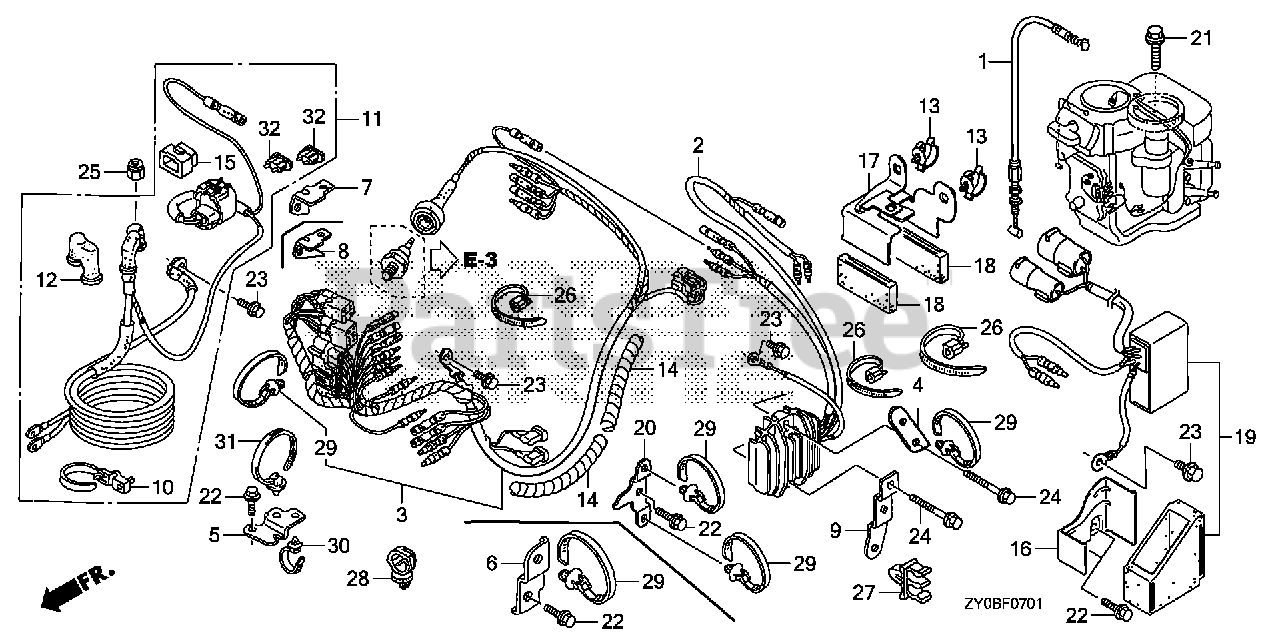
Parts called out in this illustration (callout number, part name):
1	CABLE, NEUTRAL STARTING
2	RECTIFIER ASSY., REGULATOR
3	WIRE HARNESS ASSY. (REMOTE CONTROL)(PT)
4	BRACKET, CLIP F
5	BRACKET, STARTER CABLE
8	BRACKET, FUSE CASE (PT)
9	BRACKET, E-CLIP
10	BAND, WIRE
11	CABLE ASSY., STARTER (PT)
12	COVER, MAGNETIC SWITCH TERMINAL
13	CLAMP, WIRE
14	TUBE, SPIRAL A
15	COVER ASSY., FUSE (20A)
16	BRACKET, RELAY (PT)
17	BRACKET, CONNECTOR A
18	GROMMET, CONNECTOR
19	RELAY ASSY., POWER TILT
20	BRACKET, HARNESS CLIP
21	BOLT, FLANGE (6X20)
22	BOLT, FLANGE (6X14) (CT200)
23	BOLT, FLANGE (6X12)
24	BOLT, FLANGE (6X26) (CT200)
25	NUT, LOCK (6MM)
26	TIE, CABLE
27	CLIP, FUEL TUBE
29	CLIP, HARNESS BAND (151.5MM) (NATURAL)
30	BAND, WIRE HARNESS (123.5MM) (BLUE)
31	BAND, WIRE HARNESS (93.5MM) (WHITE)
32	FUSE, BLADE (20A)
